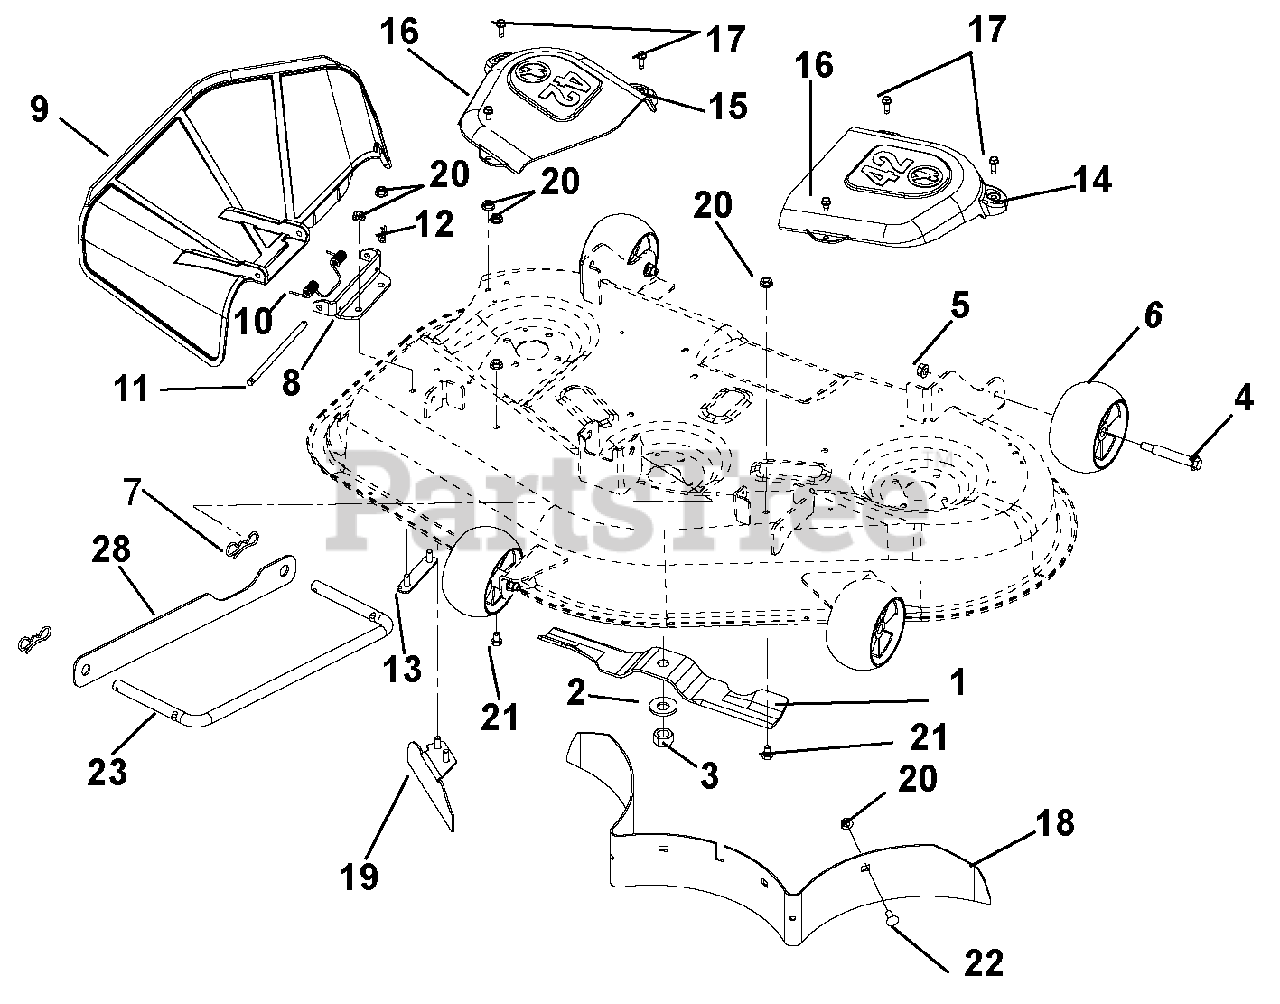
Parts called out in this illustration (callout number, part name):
1	Mower Blade, 14.83"
2	Washer, Bellville .63 x 1.625 x .14
3	Nut, Hex .62-18
4	Bolt, Shoulder .38-16 x 2.50 Hex Washer Head
5	Nut, Locking Top Flange .38-16
6	Anti-Scalp Wheel, 5 x 3 OS
7	Pin, Bow Tie Locking Cotter .091 x 1.875
8	Bracket, Discharge Chute Mount 42"
9	Discharge Chute – Molded
10	Spring, Torsion
11	Pin, 5/16 x 5.80"
12	Pin, Hair Internal .08 x .18 x 1.18
13	Weldment, Discharge Chute MT. Strap
14	Belt Cover, Left Hand 42"
15	Belt Cover, Right Hand 42"
16	Screw, Tapping .25-20 x .50 Hex Washer Head
17	Screw, Tapping .25-20 x .75 Hex Washer Head
18	Baffle, 42 Rear
19	Weldment – Baffle, Discharge 42"
20	Nut, Locking Top Flange .31-18
21	Bolt, Hex .31-18 x .50
22	Bolt, Round Head Square Neck .31-18 x .75
23	Wireform, Drag Link
24	Bolt, Hex .38-16 x 3.50
25	Washer, Flat Steel .406 x .812 x .065
26	Nut, Locking Center Jam .375-16
27	Nut, Locking Nylon Flange .38-16
28	Strap, Drag Link
